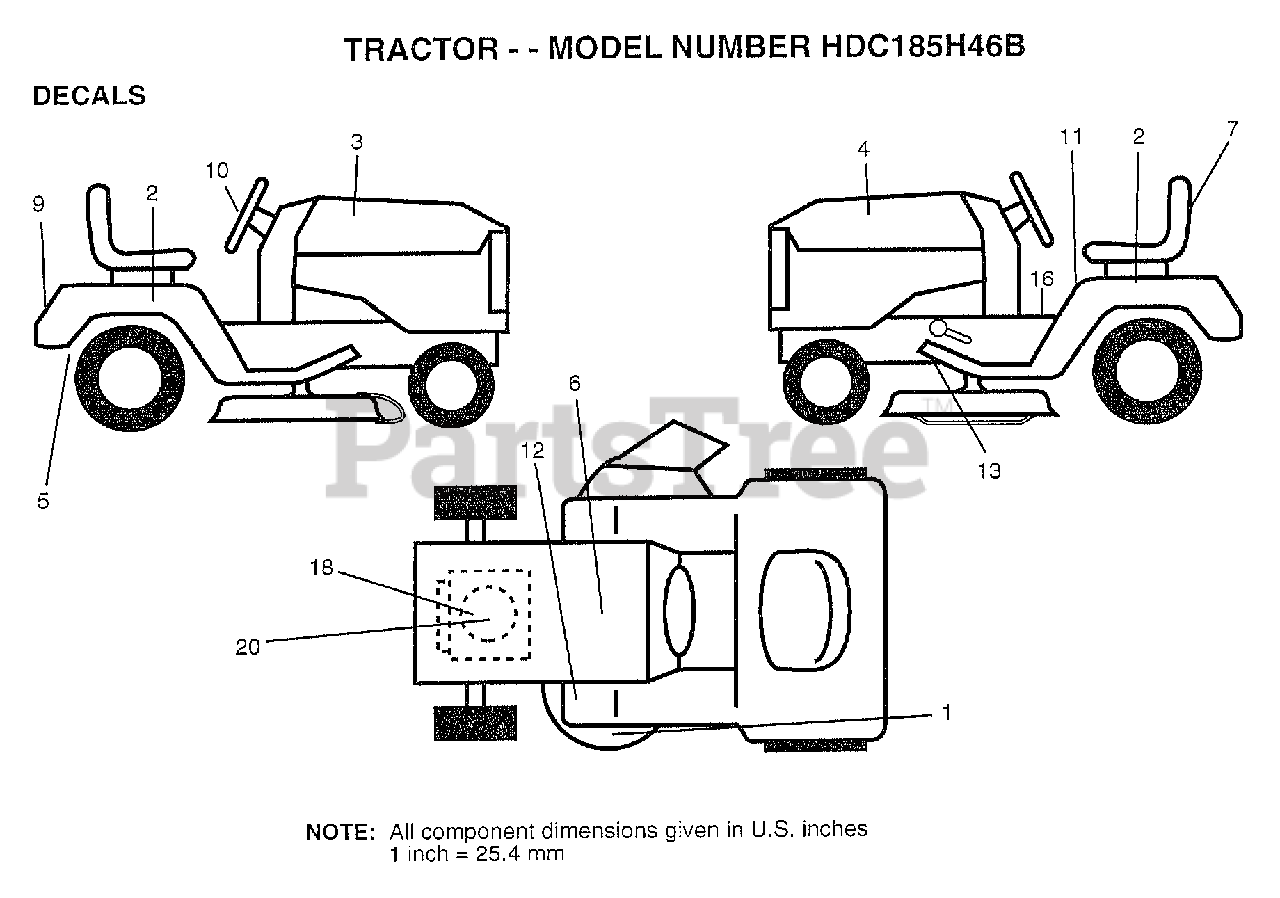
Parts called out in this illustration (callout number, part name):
1	"DECAL DECK,MULCH"
2	DECAL FENDER SIDE
3	"DECAL-HOOD,RH"
4	DECAL HOOD LH
5	DECAL DRAWBAR LH
6	DECAL.BATRY.3-3908
7	DECAL SEAT REPLCM
9	"DECAL FENDER,LOGO"
10	"DECAL WHEEL,STEER"
11	"DECAL FENDER,DANG"
12	DECAL CLUT/BRAKE
13	"DECAL.V.BELT.44"""
16	"DECAL-SADDLE,INST"
18	DECAL, HP ENGINE
20	DECAL ENG REPLCMT
